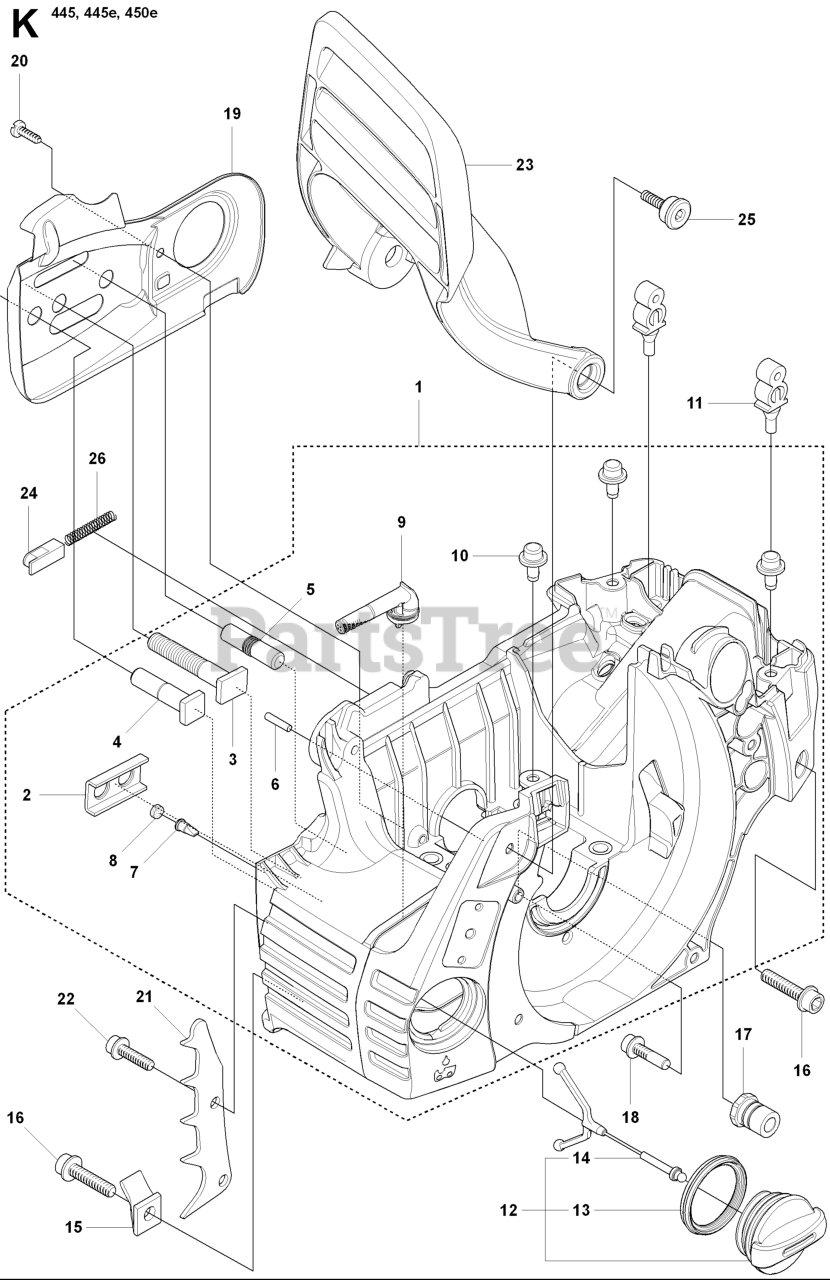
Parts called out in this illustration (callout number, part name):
2	STIFFENING PLATE
7	VALVE-CHECK (DUCKBILL)
8	PLUG
9	OIL SCREEN
11	SUPPORT
12	TANK CAP ASSY
13	SEALING
15	CHAIN CATCHER
16	SCREW IHSCFT
17	LATERAL SUPPORT
18	SCREW IHSCFT
19	CHAIN GUIDE PLATE
23	HAND GUARD
25	SCREW
26	LOCK SPRING
